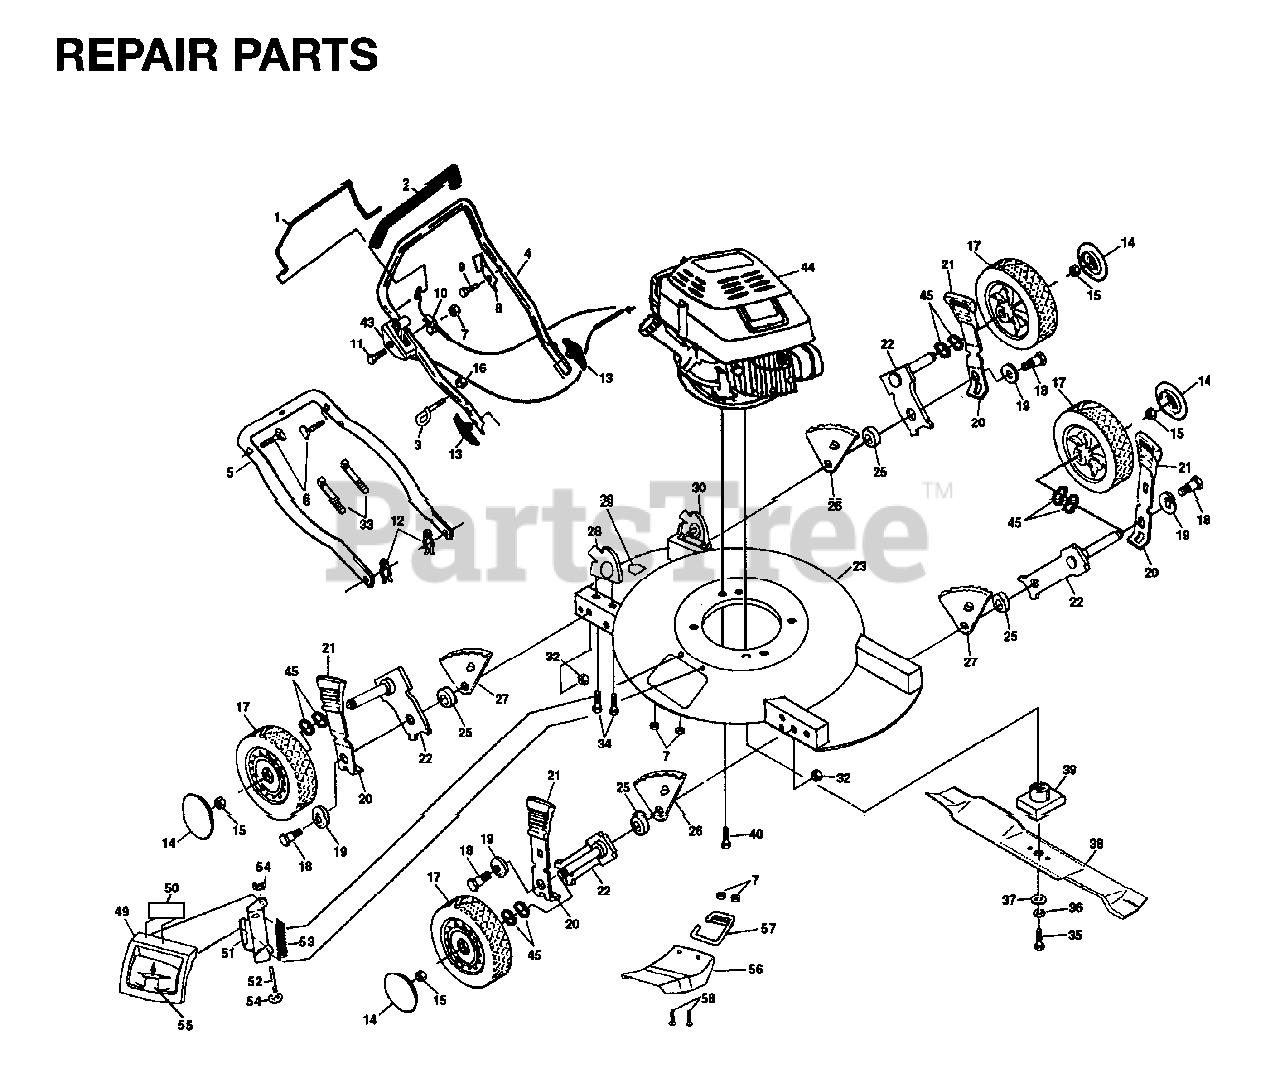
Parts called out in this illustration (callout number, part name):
1	CONTROL BAR/BLACK
2	HANDLE GRIP
3	ROPE GUIDE
5	LOWER HANDLE
6	HANDLE BOLT
7	NUT.CROWNLOCK.1/4
8	BRACKET UPSTOP
10	ENGINE ZONE CONTROL CABLE
11	SCREW 1/4-20 X 2.12
12	HAIRPIN COTTER
13	HANDLE KNOB
14	HUB CAP PM
15	HEX FLANGE LOCKNT
16	NUT.CROWNLOCK.1/4
18	BOLT
19	BELLEVILLE WASHER
20	SELECTOR SPRING
21	SELECTOR KNOB
22	AXLE ARM ASSY FT
25	SPACER PM
28	HANDLE BRKT ASSY RH
30	HANDLE BRKT ASSY LH
32	LOCKNUT
33	TIE GUIDE
34	SCREW
35	SCREW, HEX HD 3/8-24 X 1-3/8
36	LOCKWASHER
37	WASHER,HARDEN
38	BLADE.20.MULCH.(50DK,6020MD)
39	RP BLADE ADAPTOR
40	BOLT
43	THROTTLE CONTROL
45	WAVE WASHER
49	MULCHER DOOR
51	BRACKET HSG ASSY
53	SPRING PM
55	DOOR LATCH
56	MULCHER DEFLECTOR
57	BRACKET.CHUTE.MTG
